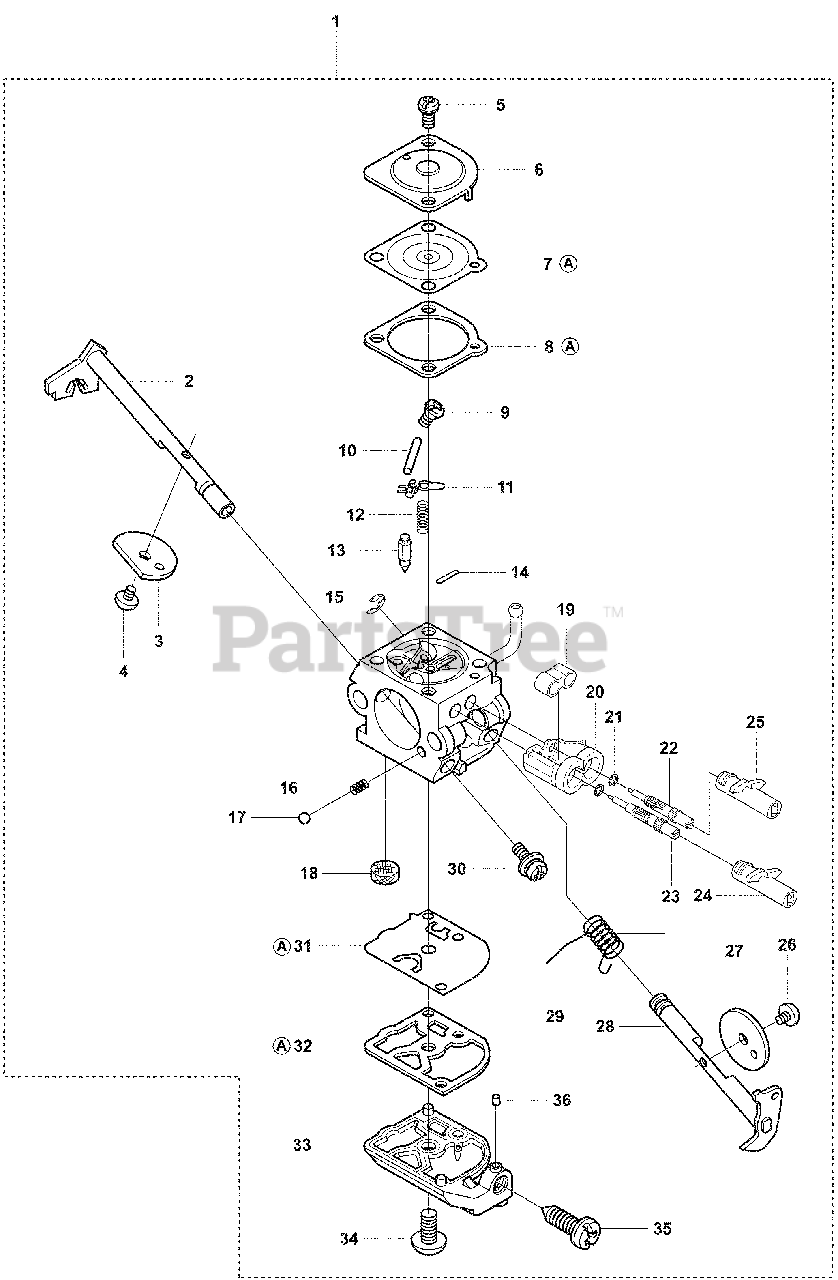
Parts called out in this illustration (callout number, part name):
1	Carburetor
7	Metering Diaphragm
8	Metering Side Gasket
10	Pin
12	Spring
13	Inlet Needle
22	NEEDLE LOW SPEED
23	NEEDLE HIGH SPEED
24	LIMITER CAP
25	LIMITER CAP
27	THROTTLE FLAP
29	Throttle Spring
31	Pump Diaphragm
